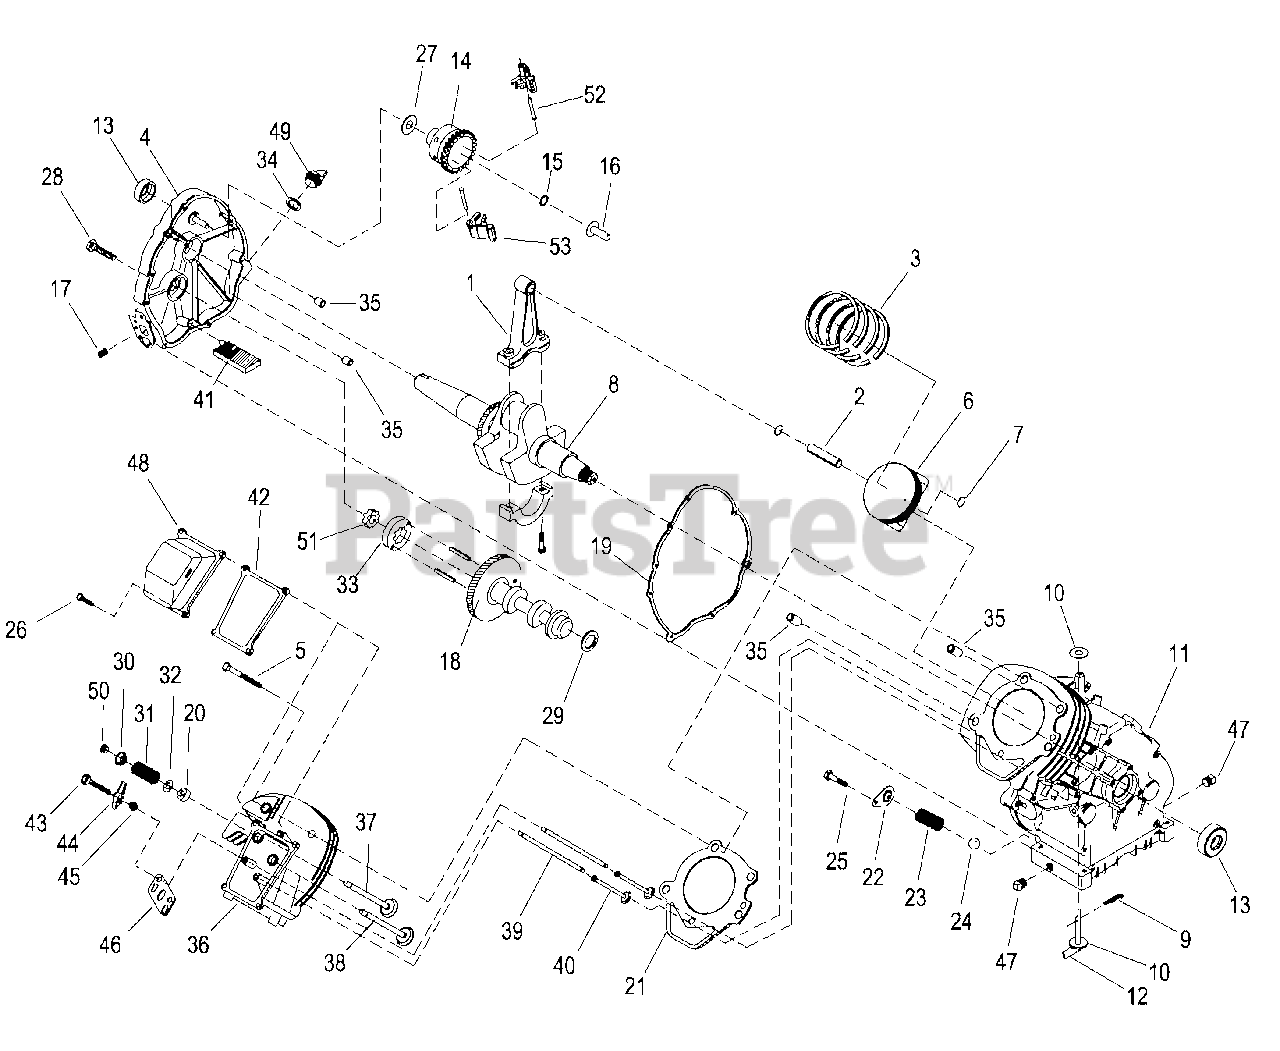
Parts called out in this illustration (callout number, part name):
1	ASSY, CONNECTING ROD
2	PIN, PISTON
3	RING SET, 75 DIAMETER
4	ASSY, GEAR COVER
5	SCREW, HHC M8-1.25 X 56
6	PISTON, COATED 75 DIAMETER
7	RETAINER, PISTON PIN
8	ASSEMBLY, CRANKSHAFT
9	PIN, "R"GOVERNOR ARM
10	WASHER, FLAT 1/4", 0.15 THICK
11	CRANKCASE GH220 HS
12	ARM, GOVERNOR
13	SEAL, 28mm DIA x 41.47 VITON
14	ASSY, GOVERNOR GEAR
15	C-RING, GOVERNOR GEAR RETAINING
16	SPOOL, GOVERNOR MACHINED
17	PLUG, 1/8" NPTF PIPE
18	ASSY, CAMSHAFT 220 W/ COMP. RELEASE
19	GASKET, CRANKCASE
20	SEAL, VALVE STEM
21	GASKET, CYLINDER HEAD GH220
22	COVER, OIL PRESSURE RELIEF
23	SPRING, OIL PRESSURE RELIEF GH220
24	BALL, 11/32" DIAMETER PRESSURE RELIEF
25	SCREW, HHTT M5-0.8 X 10
26	SCREW, M6-1.0 x 12 W/LOCK WASHER
27	WASHER, THRUST GOVERNOR GEAR
28	SCREW, HHFC M8-1.25 x 35
29	WASHER, SPRING
30	RETAINER, VALVE
31	SPRING, VALVE
32	WASHER, VALVE SPRING WEAR
33	GEROTOR, OUTER
34	O-RING, 11/16-7-8" 75 DUROMETER VITON
35	SLEEVE, DOWEL PIN 12mm DIAMETER
36	ASSEMBLY, HEAD GUIDES & SEATS 220
37	VALVE, EXHAUST
38	VALVE, INTAKE
39	PUSHROD, 145.76 LENGTH GH220
40	TAPPET, 7.5mm DIAMETER
41	ASSEMBLY, OIL PICK UP GH220
42	GASKET, VALVE COVER
43	STUD, ROCKER ARM PIVOT
44	ARM, ROCKER GH220
45	NUT, JAM M-6 – 0.75 FINE THD
46	PLATE, PUSHROD GUIDE
47	PLUG, 1/4" NPTF PIPE
48	ASSEMBLY, VALVE COVER STEEL
49	PLUG, OIL FILL PLASTIC
50	KEEPER, VALVE SPRING
51	GEROTOR, INNER
52	PIN, GOVERNOR FLYWEIGHT RETAINER
53	FLYWEIGHT, GOVERNOR
